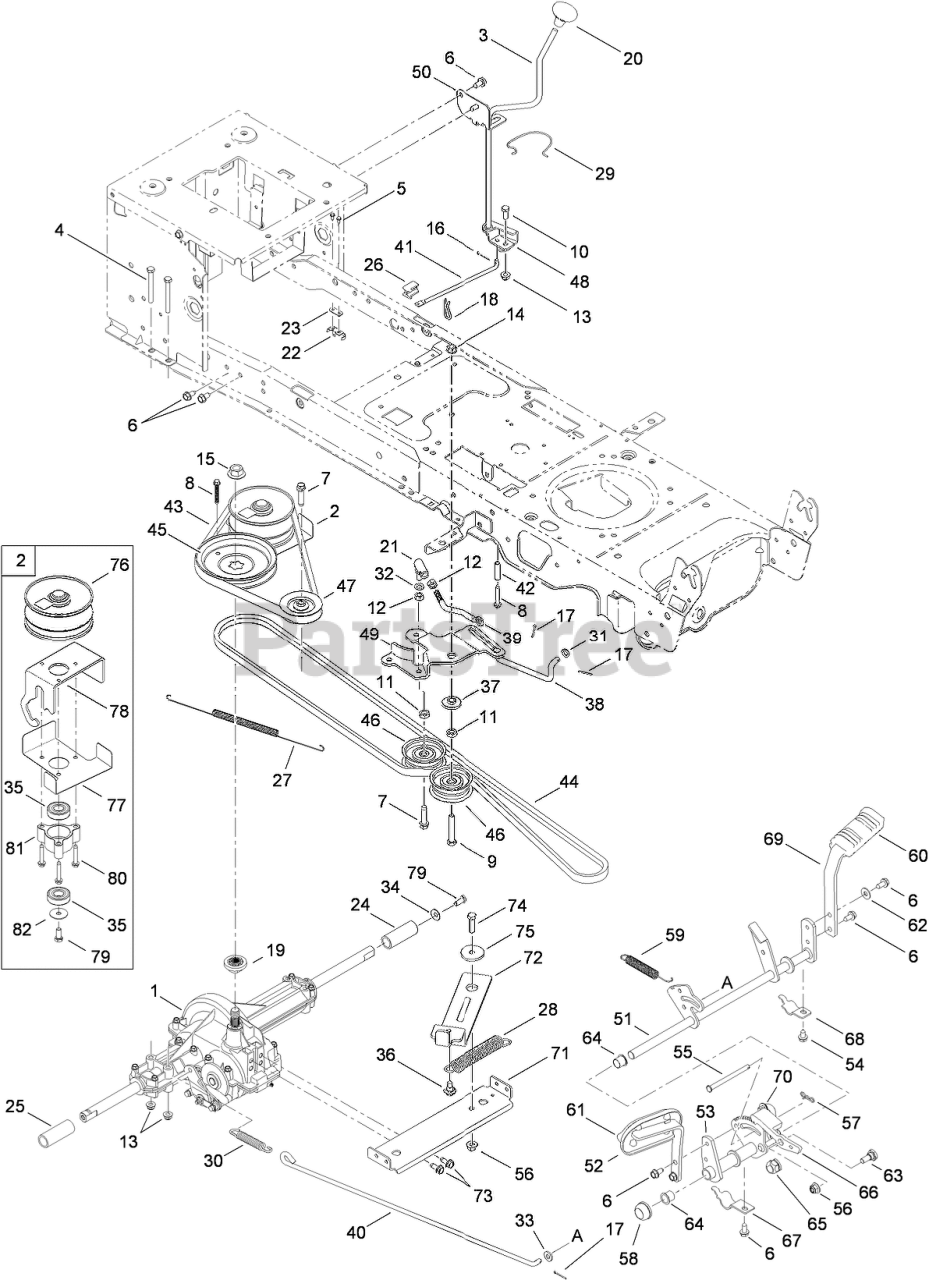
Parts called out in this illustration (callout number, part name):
1	TRANSMISSION DRIVE ASM
2	Pulley and Bracket ASM
3	SHIFT LEVER ASM
4	SCREW-HEX
5	SCREW-HWHTF
6	SCREW-TAP
7	SCREW-TAP
8	SCREW-HH
9	SCREW-HH
11	NUT-JAM
12	NUT-HEX
13	NUT-LOCK, FLANGE
14	NUT-LOCK, FLANGE
15	NUT-FLANGE
16	PIN-COTTER
17	PIN-COTTER
18	PIN-HAIR
19	HUB-PULLEY, SPLINE
20	KNOB-SHIFT
21	BALL JOINT ASM
22	SWITCH-SPRING, SHORT
23	PLATE-INSULATOR
24	SLEEVE
25	SLEEVE
26	BEARING-PLATE, SHIFT
27	SPRING-EXTENSION
28	SPRING-EXTENSION
29	CLIP-SPRING, SHIFTER
30	SPRING-EXTENSION
31	WASHER-FLAT
32	WASHER-LOCK
33	WASHER-FLAT
34	WASHER-BELL
35	BEARING-BALL
36	BOLT-SHOULDER, TAP
37	SPACER-SHOULDER
38	ROD-BYPASS, FOOT PEDAL
39	ROD-ADJUSTMENT, IDLER
40	ROD-BRAKE
41	ROD-SHIFT
42	SPACER
43	BELT-V, POLY
44	BELT-DRIVE, VARIABLE SPEED
45	PULLEY-V (W/HUB)
46	PULLEY-IDLER, FLAT
47	PULLEY-IDLER, Y TYPE
48	BRACKET-ADJUSTMENT, SHIFT
49	BRACKET-IDLER, CENTER DOUBLE
50	BRACKET-SHIFT
51	BRAKE CONTROL ASM
52	PEDAL ASM
53	PEDAL BRACKET ASM
54	SCREW-HWH
55	PIN-CLEVIS
56	NUT-LOCK, FLANGE
57	PIN-COTTER
58	CAP-PUSH
59	SPRING-EXTENSION
60	PAD-PEDAL, BRAKE
61	PAD-PEDAL
62	WASHER-BELL
63	BOLT-SHOULDER
64	BEARING-FLANGE
65	BEARING-FLANGE, HEX (SPLIT)
66	LATCH-CRUISE
67	BRACKET-STRAP, PEDAL SUPPORT
68	BRACKET-STRAP, PEDAL SUPPORT
69	BRACKET-PEDAL, BRAKE
70	BRACKET-PLATE, REINFORCEMENT
71	BRACKET-TRANSMISSION
72	BRACKET-IDLER
73	SCREW-HWH
74	SCREW-HH
75	SPACER-SHOULDER
76	PULLEY ASM
77	BELT KEEPER ASM
78	BRACKET ASM
79	SCREW-HH
80	SCREW-HWH
81	CUP-BEARING
82	WASHER-FLAT
